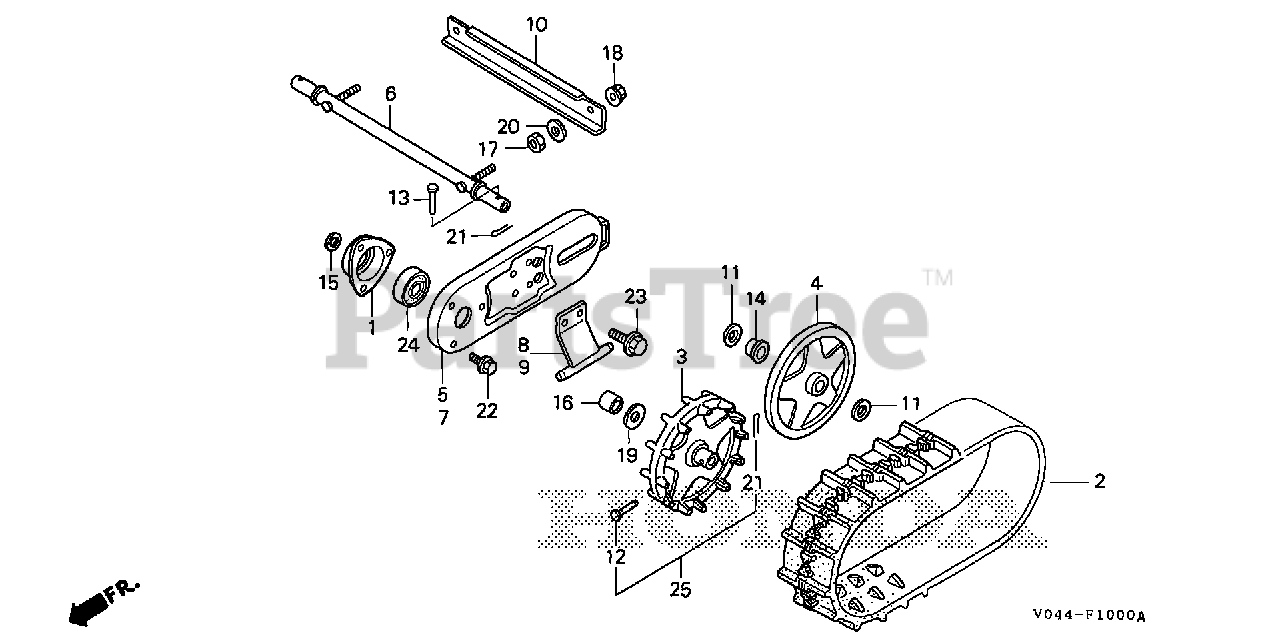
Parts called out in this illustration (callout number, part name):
1	HOLDER, WHEEL SHAFT BEARING
2	CRAWLER (12-60X20 B-122)
3	SPROCKET, CRAWLER
4	ROLLER, CRAWLER (COO)
4	ROLLER, CRAWLER
5	PLATE, R. CRAWLER
6	PIPE, CRAWLER
7	PLATE, L. CRAWLER
8	GUIDE, R. CRAWLER
9	GUIDE, L. CRAWLER
10	BAR, CRAWLER PLATE
11	WASHER, PLAIN (22MM)
12	PIN (6.2X38)
14	COLLAR, CRAWLER PIPE
15	COLLAR, R. WHEEL SHAFT
16	COLLAR, CRAWLER SPROCKET
17	NUT, FLANGE (10MM)
18	NUT, FLANGE (10MM)
19	WASHER, PLAIN (20MM)
20	WASHER, PLAIN (10MM)
21	PIN, COTTER (3.0X18)
22	BOLT, FLANGE (6X12) Use up to Engine SN 1543277.
23	BOLT, FLANGE (8X14)
24	BEARING, RADIAL BALL (6004UU)
25	PIN SET, CRAWLER
